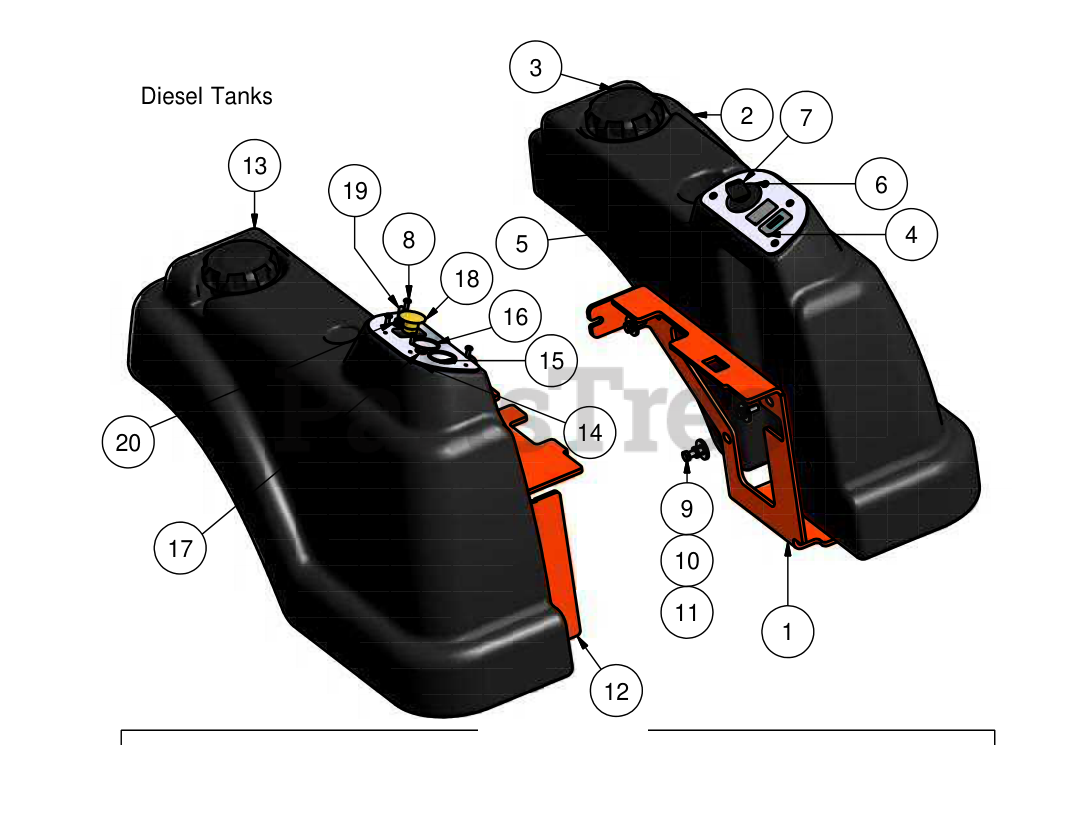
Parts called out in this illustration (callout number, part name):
1	Left Fuel Tank Swing Support
2	Left Fuel Tank with Fender
3	Diesel Fuel Cap
4	Hourmeter-Diesel
5	Diesel Control Panel (Left)
6	Ignition Switch
7	Ignition Key
8	10mm x 32 x 1" Bolt
9	5/16" x 1" Hex Bolt
10	5/16" Lock Washer
11	1 5/16" Flat Washer
12	Right Fuel Tank Support
13	Right Fuel Tank with Fender
14	Diesel Control Panel (Right)
16	Temperature Guage
18	PTO Engager
19	Deck Lift Joystick
20	Joystick Cover
